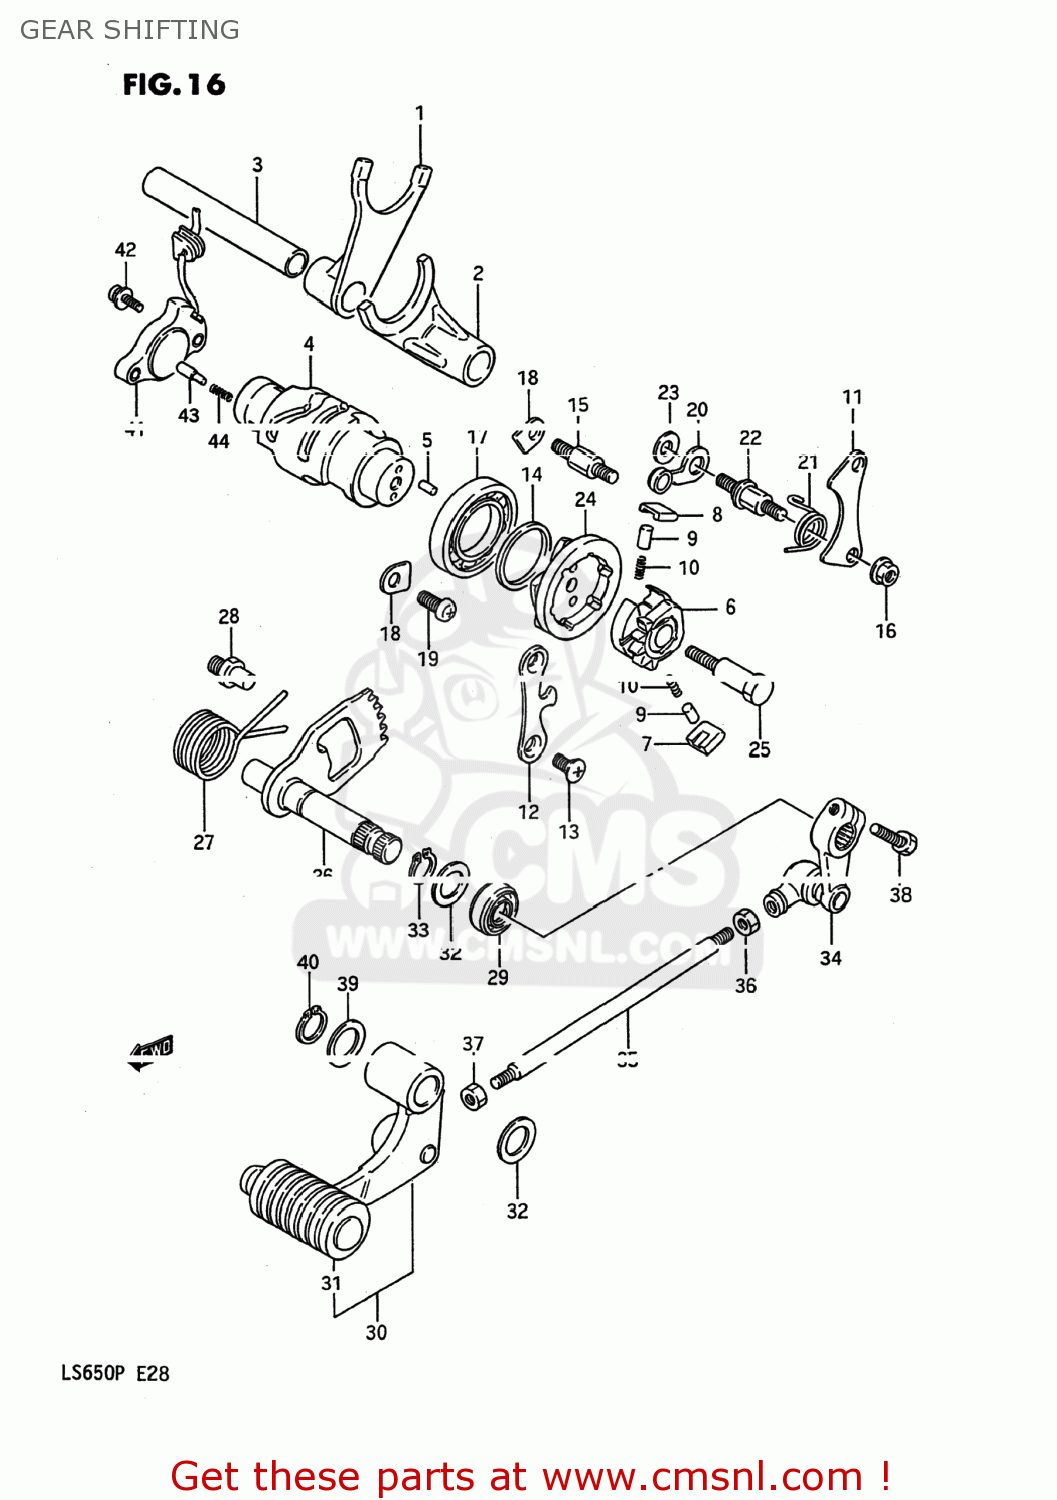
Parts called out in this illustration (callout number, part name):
1	FORK,GEAR SHIFT NO.1
2	FORK,GEAR SHIFT NO.2
3	SHAFT,GEAR SHIFT FORK
4	CAM,GEAR SHIFT
5	PIN
6	GEAR,GEARSHIFT CAM DRIVE
7	PAWL,GEAR SHIFT NO.1
8	PAWL,GEAR SHIFT NO.2
9	PIN(5X8)
10	SPRING
11	LIFTER,GEAR SHIFT POLE
12	GUIDE,GEAR SHIFT CAM
13	SCREW
14	WASHER(25X32X3)
15	BOSS,SHIFT PAWL LIFTER
16	NUT
17	BEARING
18	RETAINER,SHIFT CAM,R BEARING
19	SCREW 6X12
20	STOPPER,GEAR SHIFT CAM
21	SPRING
22	SUPPORT,CAM STOPPER ARM
23	WASHER
24	PLATE,GEAR SHIFT CAM
25	PIN,SHIFT CAM DRIVEN GEAR
26	SHAFT,GEAR SHIFT
27	SPRING
28	STOPPER,GEAR SHIFT CAM
29	OIL SEAL
30	LEVER ASSY,GEAR SHIFT
31	RUBBER,GEAR SHIFT PEDAL
32	WASHER(12.5X20X1)
33	CIRCLIP,12 MM
34	ARM,GEAR SHIFT LINK
35	ROD,GEAR SHIFT LINK
36	NUT
37	NUT 6MM
38	BOLT
39	WASHER
40	CIRCLIP,12 MM
41	BASE ASSEMBLY,NEUTRAL SWITCH TERMINAL
42	SCREW
43	PIN(5X15.5)
44	SPRING
